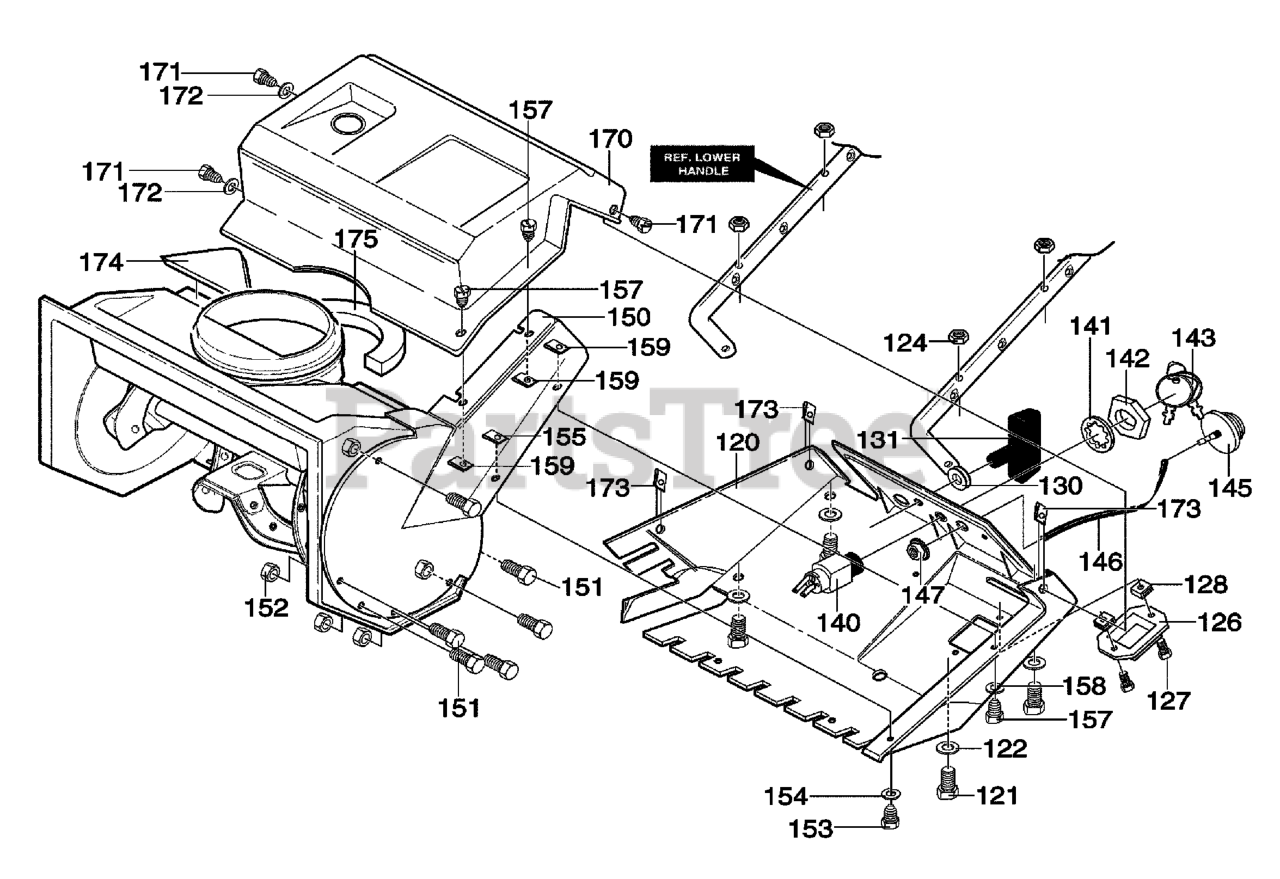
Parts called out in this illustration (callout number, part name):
120	COVER, BOTTOM
121	SCREW, 1/4-20X1.25
122	WASHER, FLAT
124	NUT, 1/4-20
126	COVER, CARB
127	SCREW, 1/4-14X.75
128	NUT, 1/4-10 SPEED J TYPE
130	GROMMET & WASHER, ROPE GUIDE
131	KNOB, STAND TEE
140	SWITCH, IGNITION
141	WASHER
142	NUT, 5/8-32 ACC
143	2 KEYS & RING
145	PRIMER, ENGINE
146	HOSE, PRIMER
147	NUT, 1/4-20
150	COVER, BELT
151	SCREW, 10-24X.50
152	NUT, #10-24
153	SCREW, 1/4-20X.50
154	WASHER, FLAT
155	NUT, 1/4-20
157	SCREW, 1/4-14X.75
158	WASHER, FLAT
159	NUT, 1/4-20
170	COVER, TOP
171	SCREW, 1/4-14X.75
173	NUT, 1/4-10
174	SEAL, STRIP
175	SEAL, STRIP CHUTE & GAS SEAL
